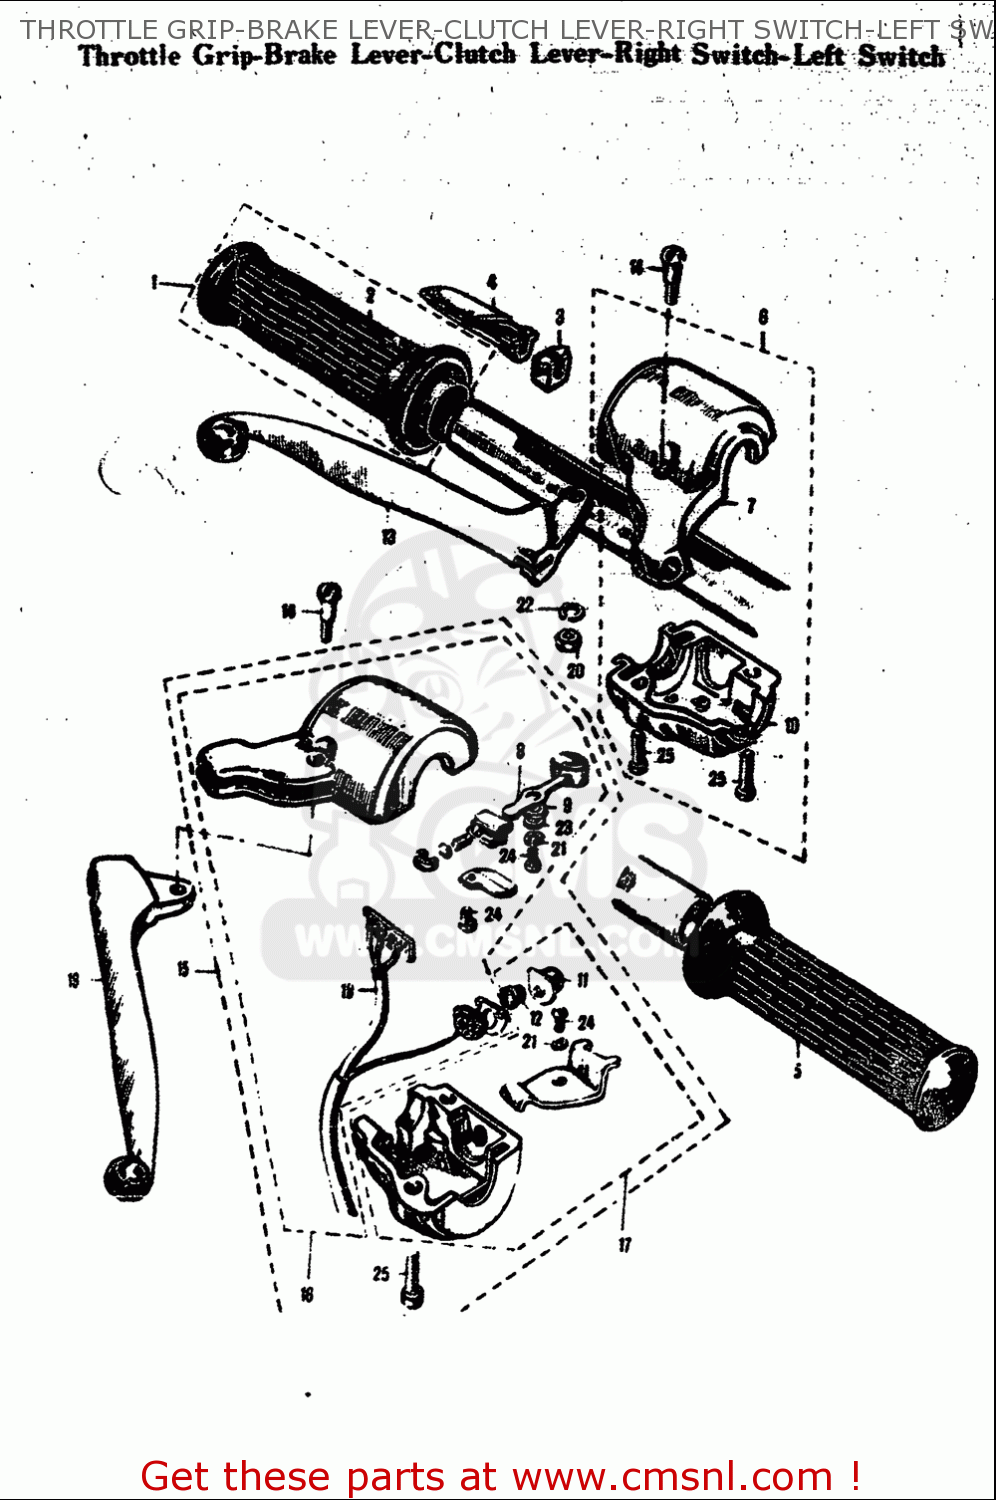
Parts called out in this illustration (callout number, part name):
11	BUTTON
12	SPRING
20	NUT
21	WASHER,LOCK
22	WASHER,LOCK
23	WASHER
25*	SCREW
